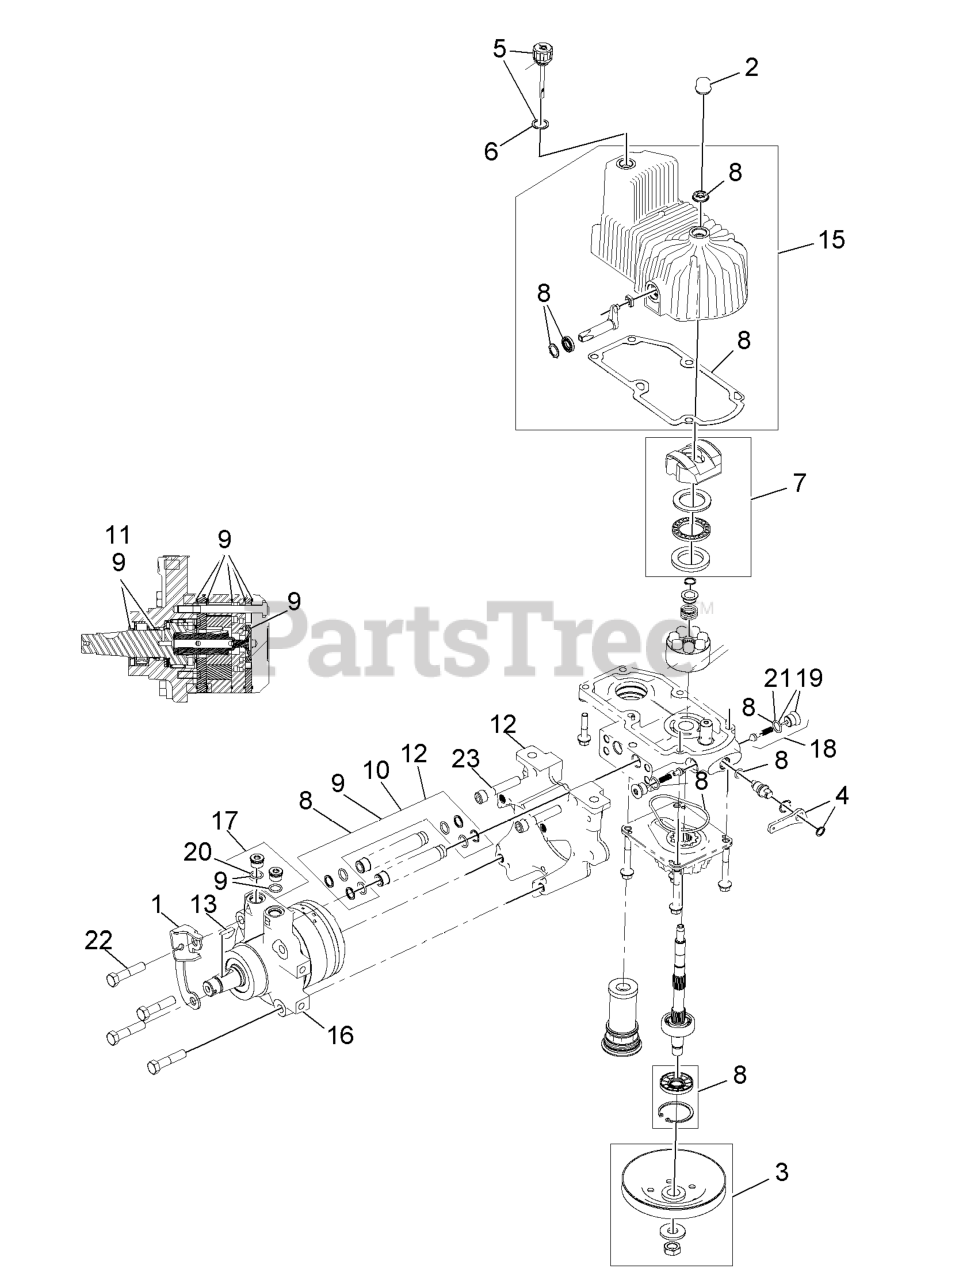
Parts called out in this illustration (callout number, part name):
1	BRACKET-ANCHOR, CABLE
2	COVER-SHAFT, HYDRO
3	PULLEY KIT
4	HANDLE-BYPASS VALVE, HYDRO
5	DIPSTICK-HYDRO W/GASKET
6	GASKET-DIPSTICK, HYDRO
7	SWASH BLOCK KIT
8	PUMP SEAL KIT
9	MOTOR SEAL KIT
10	TUBE SEAL KIT
11	OUTPUT SHAFT SEAL KIT
12	NOSE CUP-UHT
13	KEY-WOODRUFF
15	HOUSING-HYDRO, LH
16	MOTOR-HYDRAULIC LH 240CC
17	MAGNETIC PLUGS SERVICE KIT
18	CHECK VALVE ASM
19	PLUG-CHECK (W/O-RING)
21	O-RING-CHECK VALVE
22	SCREW HH
23	SCREW-HSH
